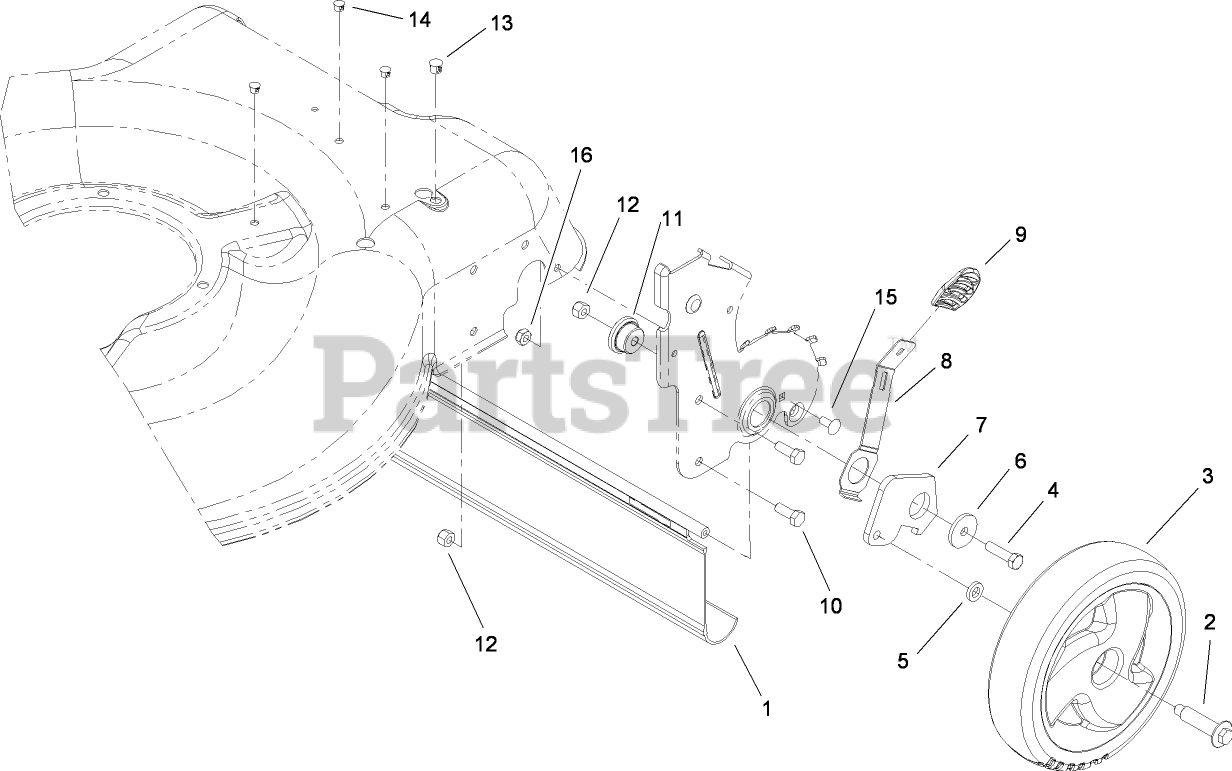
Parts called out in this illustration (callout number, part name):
1	SHIELD-TRAILING
2	BOLT-SHOULDER
3	WHEEL ASM (59505)
4	SCREW-HH
5	WASHER-BOLT, WHEEL
6	WASHER-FLAT
7	ARM-PIVOT, REAR
8	ARM-SPRING
9	KNOB-LEVER, HOC
10	SCREW-HH
11	BUSHING-MOUNT, HOC
12	NUT-LOCK, NI
13	PLUG-DOME
14	PLUG-DOME
15	SCREW-CARR
16	NUT-LOCK, NI
